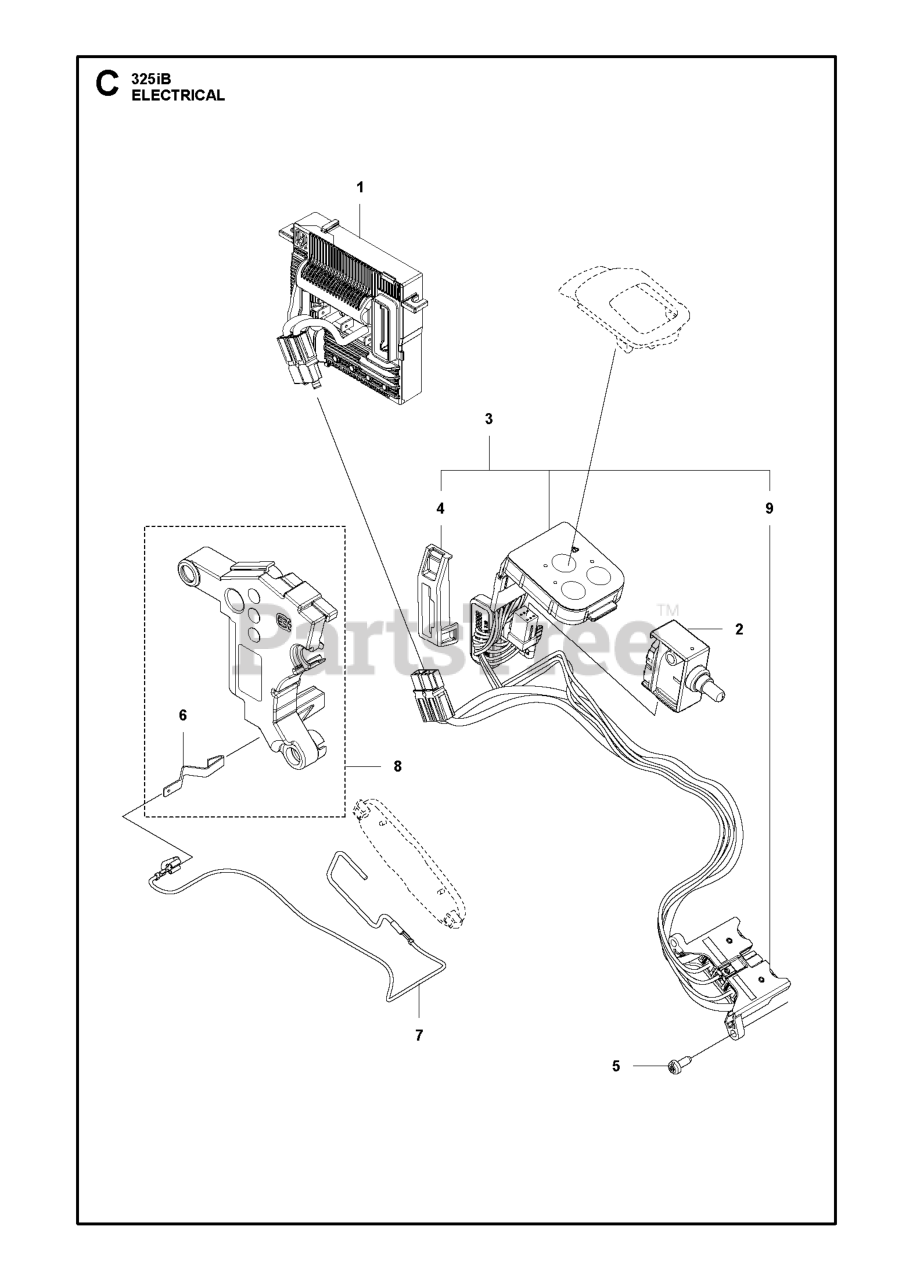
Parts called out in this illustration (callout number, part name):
1	CONTROL UNIT BLDC MID SPEC, GE
2	TRIGGER SWITCH IPX4
3	WIRING ASSY BLOWER MAIN
5	SCREW CITXPANT
7	WIRING ASSY
8	KIT COVER ELECTRONICS
9	CONNECTOR BATTERY
